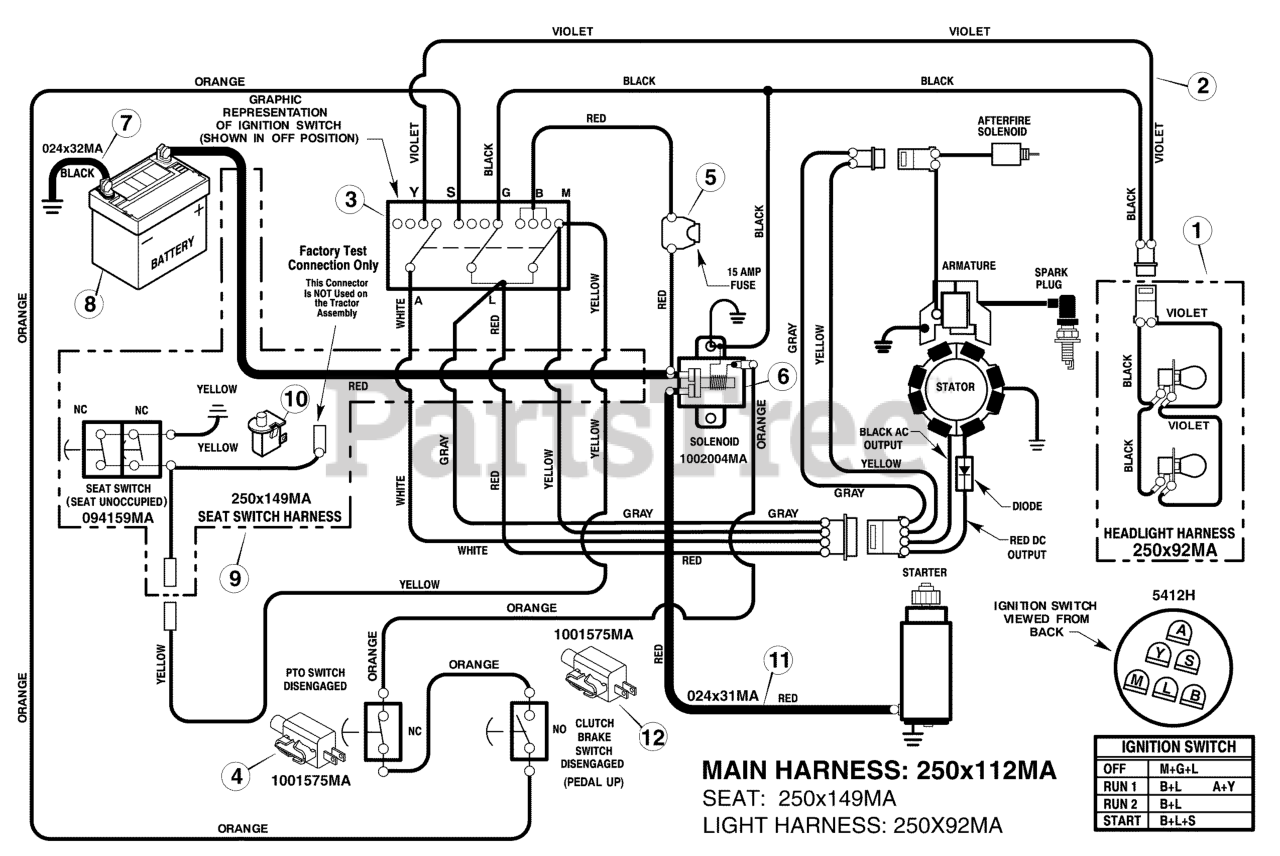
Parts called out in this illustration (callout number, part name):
1	Harness, Light Wire
2	Harness, Chassis Wire
3	Switch, Ignition
4	Switch, Limit (PTO)
6	Solenoid
7	Cable, Battery Ground
8	Battery
9	Harness, Seat Switch Wire
10	Switch, Seat Sensor
12	Switch, Select Reverse / Clutch Brake
